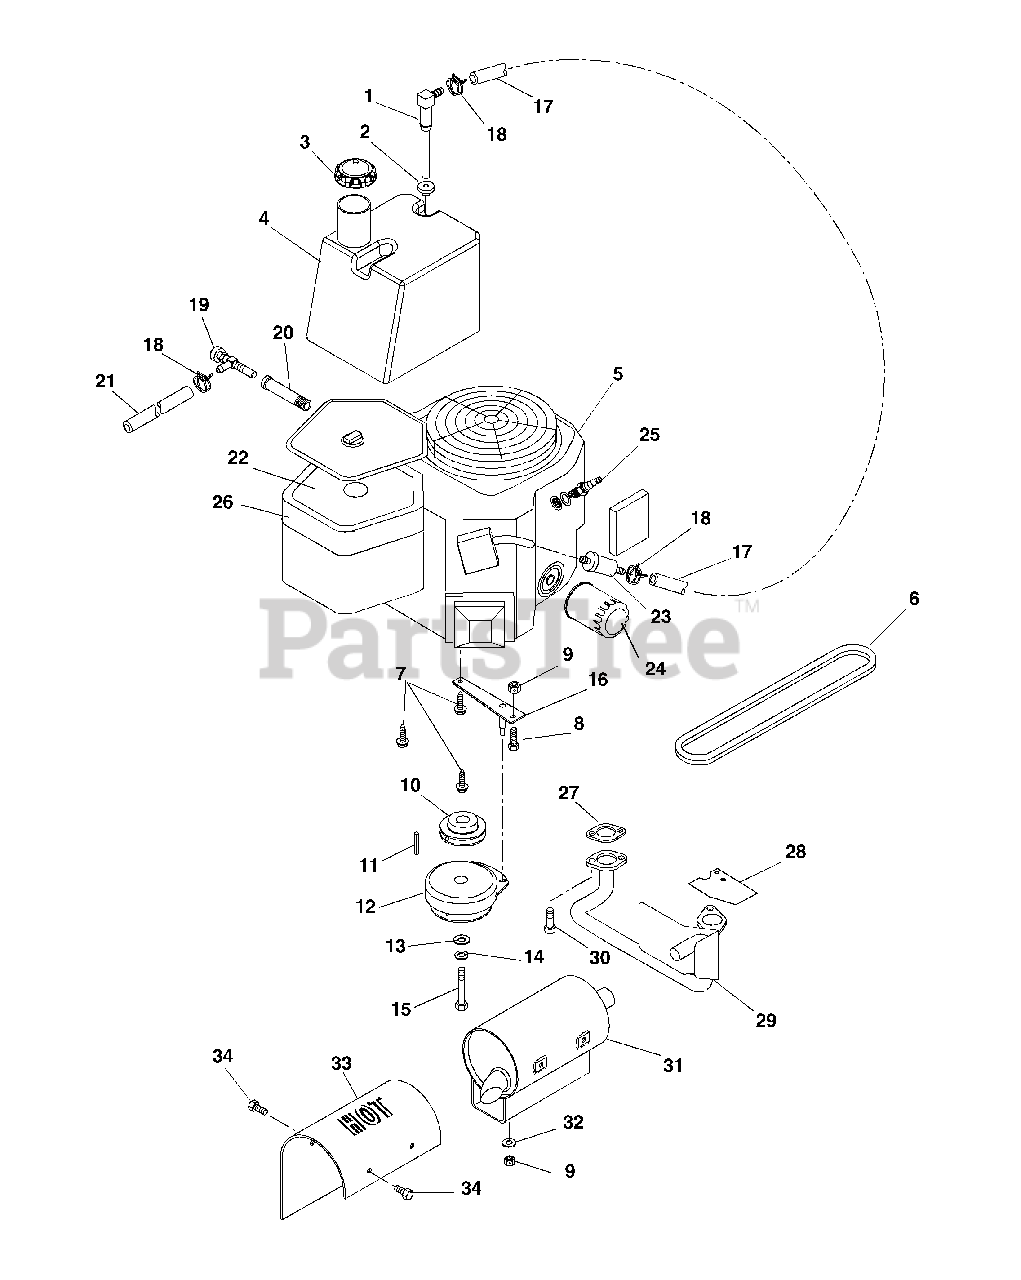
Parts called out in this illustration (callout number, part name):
1	Fitting, Tank
2	Bushing
3	Cap, Gas
4	Tank, Fuel
5	Engine, 25HP Kohler 6-Pin
5	Engine, 21HP Vanguard- 6 Pin
6	V-Belt A-Section 24.90 x .500 /.031
7	Screw-Tapping Hex-Washer-Head .38-16 x 1.00
8	Bolt-Hex .31-18 x 1.75 Grade 5
9	Nut-Locking-Center .31-18
10	Pulley-4.46 DIA x 1.12 Bore
11	Key-Square .25 x 1.00 x .25
12	Electric Clutch
13	Washer-Flat-Steel .515 x 1.625 x .250
14	Washer-Locking .44 x .109
15	Bolt-Hex .44-20 x 3.00 Grade 5
16	Anchor-Clutch
17	Gas Line-Bulk 1/4" ID
18	Hose-Clamp
19	Cock-Oil Drain
20	Adapter-Oil Drain
21	Gas Line-Bulk 1/4" ID
22	Air Filter
23	Fuel Filter
24	Oil Filter
25	Spark Plug
26	Element, Precleaner
27	Gasket-Exhaust
28	Heat Deflector
29	Manifold-Kohler CV18-25
29	Manifold-Briggs and Stratton
30	Screw-Socket Head M8-1.25 x 20 mm
31	Muffler (Includes 09066300 Heat Shield)
32	Washer, Flat-Steel
33	Heat Shield (Included with 09065600 Muffler)
34	Bolt, Hex M5 - .8 x 8 mm
